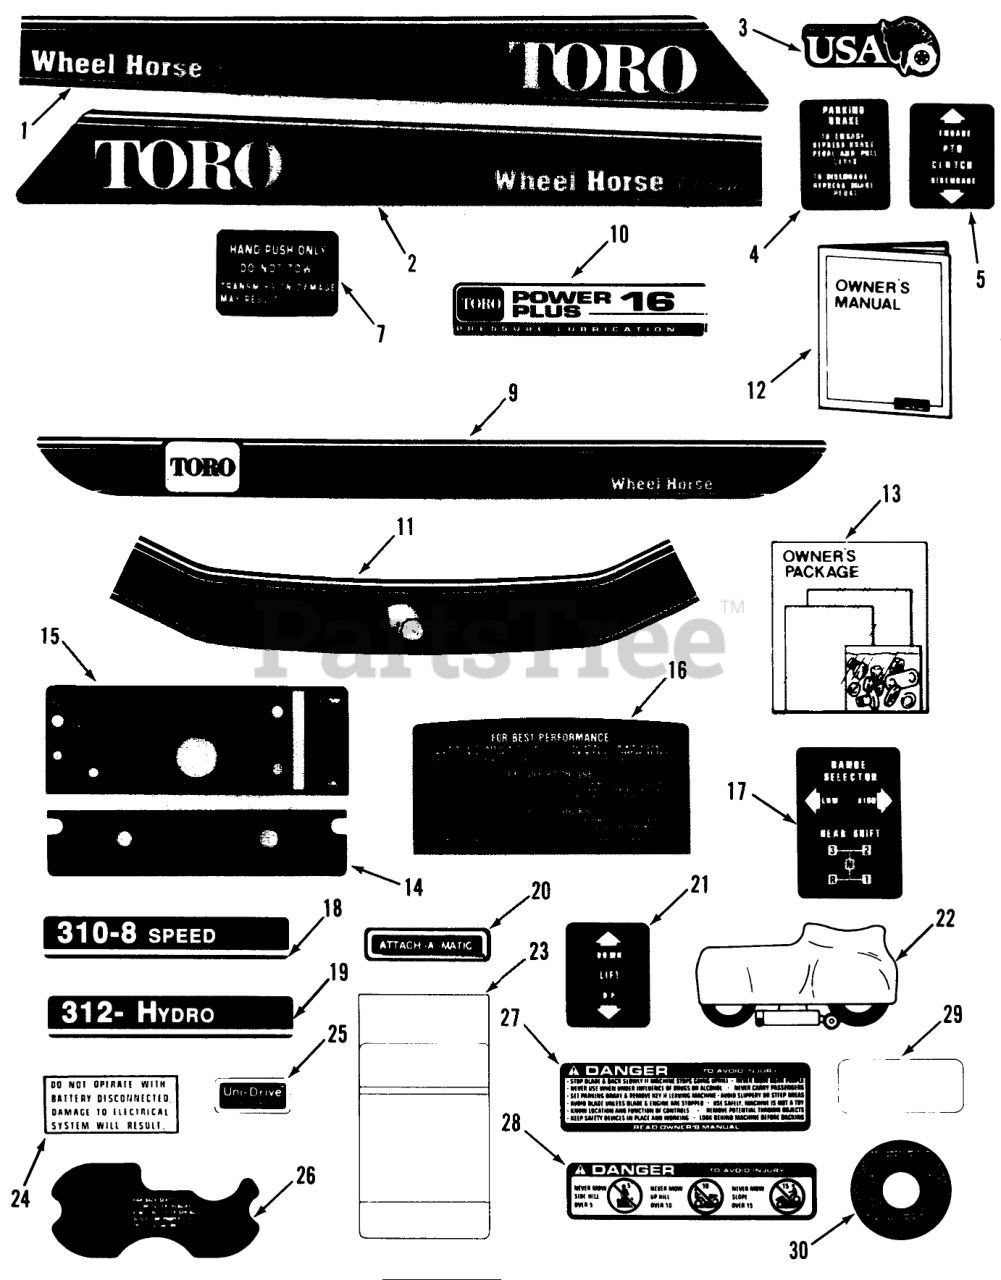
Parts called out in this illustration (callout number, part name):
1	DECAL-HOOD CLASSIC
2	DECAL-HOOD GEN 26.20
3	Decal-Made In USA
4	DECAL-PARKING, BRAKE
5	DECAL PTO CLUTCH
7	DECAL-DO NOT TOW
9	DECAL-FENDER
10	DECAL-PWR PLUS 16 PL
11	DECAL-FRONT HOOD
12	Operator-s Manual-Tractor 310-8, 312-8, 416-8
13	Loose Parts Package 310-8, 312-8
14	Decal-Switch Plate
15	DECAL-LOWER DASH
16	Decal-Rear Hood
17	DECAL-SHIFT PATTERN
18	Decal-310-8 Speed
19	DECAL-312 HYDRO
20	Decal-Attac-O-Matic
21	DECAL-LIFT
22	Vinyl Tractor Cover
23	MAINTENANCE-DECAL
24	DECAL ELECT SYSTEM
25	Decal-Unidrive
26	DECAL-SEAT LIFTER
27	DECAL-DANGER
28	DECAL-DANGER
29	DECAL-OVERLAY
30	Decal-Air Cleaner
31	DECAL-COLD START
